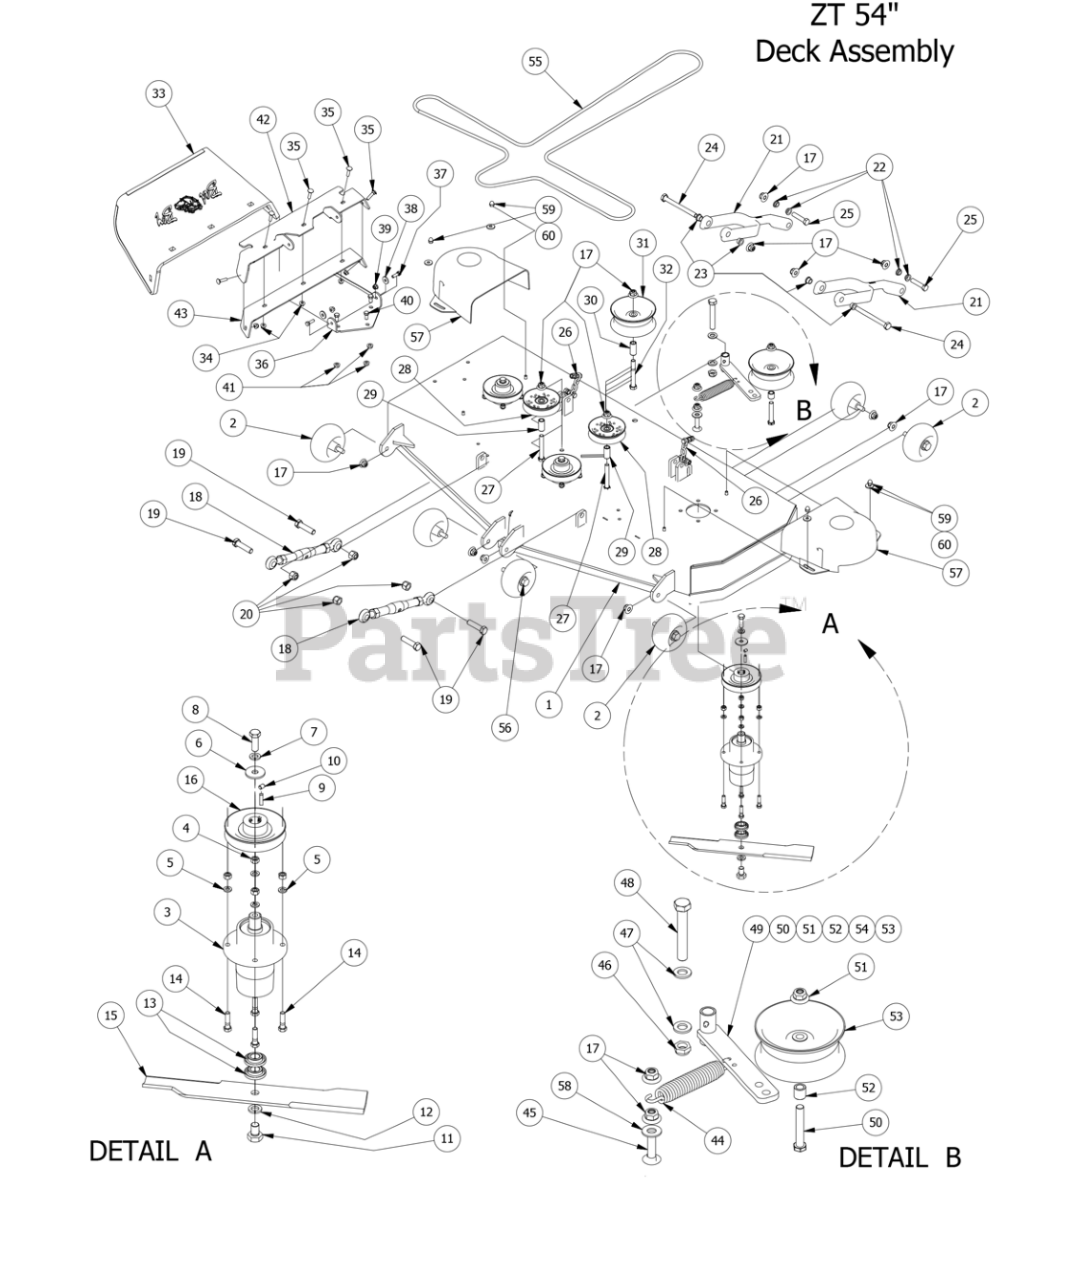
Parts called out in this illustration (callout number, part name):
1	2014 ZT/CZT 54" Deck
2	Deck Wheel
3	Spindle - Aluminum
4	3/8" Hex Nut
5	3/8" Lock Washer
6	1/2 Belleville Washer
7	1/2" Lock Washer
8	1/2"-20 x 1 1/2 - Grade 5 Fine Thread Bolt
9	1/4" x 1" Key
10	5/16 Set Screw
11	5/8" x 1 1/2" Grade 8 Bolt
12	5/8" Lock Washer
13	Spindle Bearing
14	3/8-16 X 1-1/4 GR 5 Hex Bolt
15	54" Deck Fusion Blade For Outlaw
16	5" Deck Pulley
17	1/2-13 Nylon Flange Nut-Orange
18	Turnbuckle (Top Link)
19	5/8" x 2 1/2" Hex Bolt
20	5/8 Std NC Nylock Nut
21	Deck Arm Assembly
22	Flange for Lower Deck Arm
23	Flange Bushing For Deck Arm upper
24	1/2" x 5 1/2" Bolt
25	1/2-13X 2-1/4 GR Hex Bolts
26	Chain assembly
27	1/2 x 3 1/2 Flange Bolt Grade 8
28	4-3/4 Idler Pulley
29	.502 ID X.75 OD X 1.500 Leng
30	1 3/4" Pulley Spacer
31	5 3/4" Deck Idler Pulley
32	1/2" x 4" Bolt (Grade 8)
33	Rubber Discharge Chute
34	5/16" Nylon Flange Nut
35	5/16" x 1 1/4" Carriage Bolt
36	Discharge Chute Hanger (deck mounted)
37	5/16" x 1" Bolt
38	.360 ID Plastic Washer
39	5/16" Nylon Flange Nut
40	3/8" x 3/4" Hex Bolt
41	3/8" Flange Nut
42	60" Discharge Chute Upper Hanger
43	60" Lower Hanger
44	2009 Deck/Pump Idler Spring
45	1/2 x 2" Carriage Bolt
46	5/8-11 Nylon Insert Jam Half Nut
47	.635 ID Plastic Washer
48	5/8" x 4" Hex Bolt
49	Deck Idler
50	1/2-13 x GR 5 Hex Bolt Zinc
51	1/2-13 Nylon Flange Nut-Orange
52	3/4 OD x 1/2 ID x 3\4 Length
53	5 3/4" Deck Idler Pulley
54	Deck Idler Assembly (Components 49,50,51,52,53)
55	B155.75 Belt
56	Deck Wheel Bolt
57	2014 ZT Pulley Cover
58	1/2" Washer (Grade 8)
59	Acorn nut-pulley Cover
60	.360 ID Plastic Washer-Black
